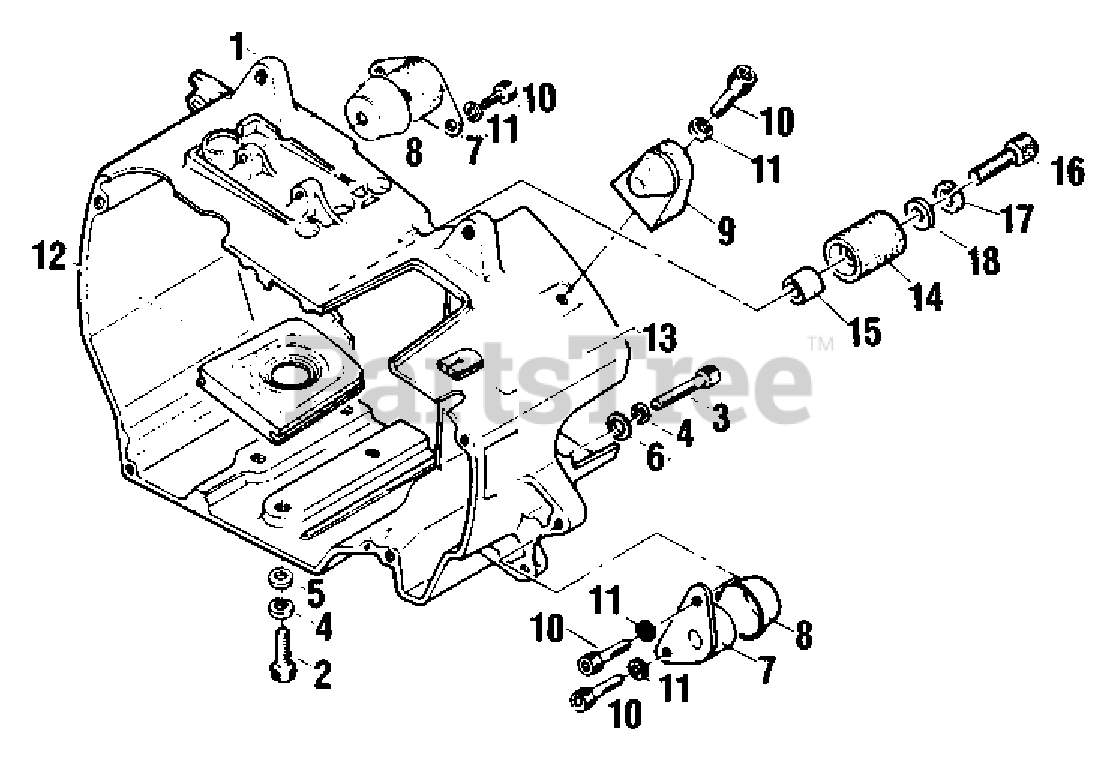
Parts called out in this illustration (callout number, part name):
1	CASE, ENGINE
2	BOLT M5×18
3	BOLT 5×25
4	WASHER, SPRING 5
5	WASHER, FLAT 5.5×10×0.8
6	WASHER
7	CUSHION 5
8	HOLDER
9	CUSHION 5
10	BOLT 5×12
11	WASHER, SPRING 5
12	SEAL
13	GROMMET
14	CATCHER, CHAIN
15	BUSHING
16	BOLT 5×25
17	WASHER, SPRING 5
18	WASHER
